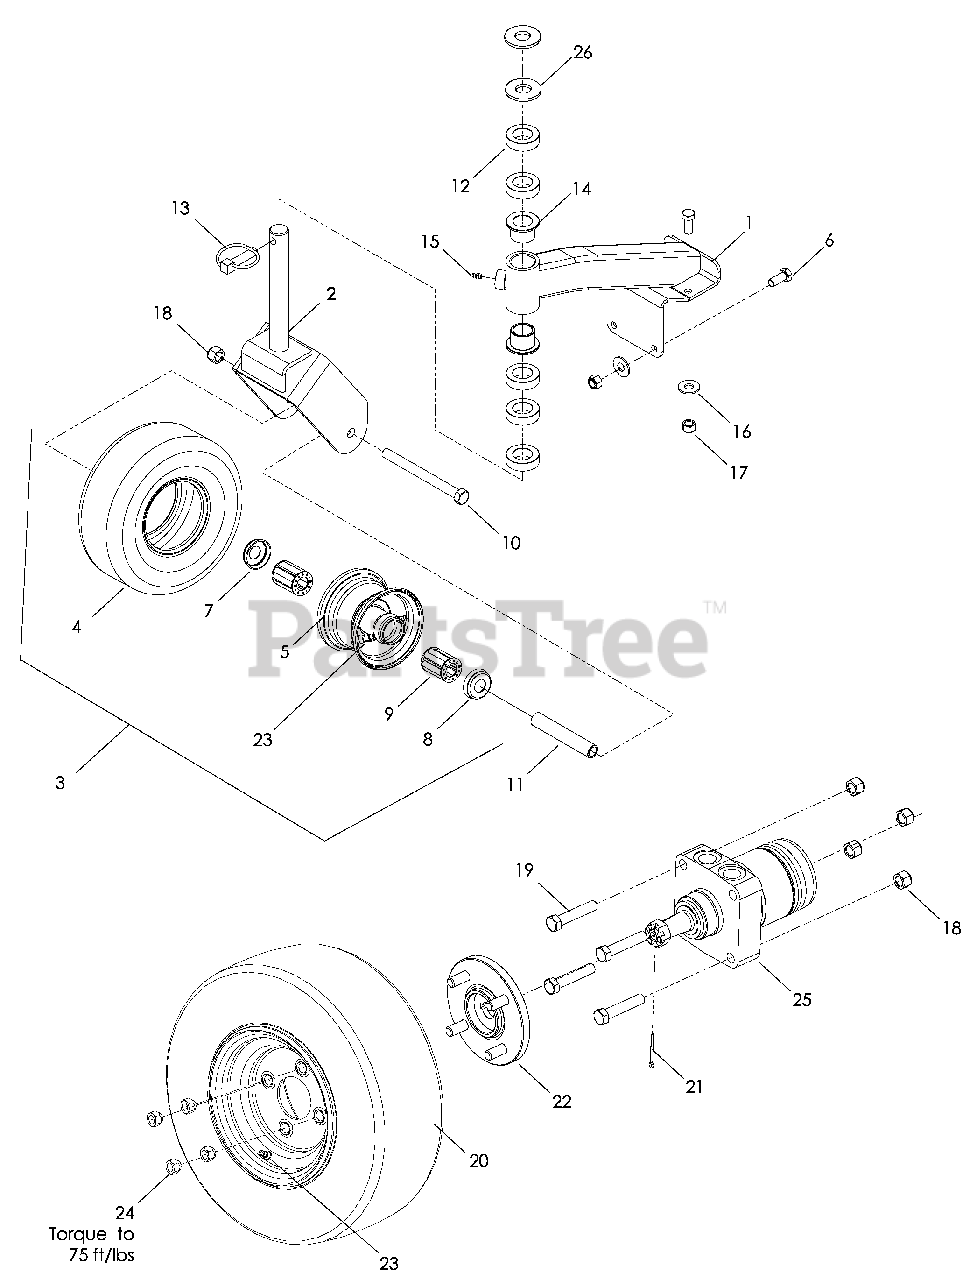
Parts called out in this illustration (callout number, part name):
1	CASTER ARM
2	CASTER FORK
3	WHEEL ASSEMBLY, CASTER
4	TIRE, CASTER
6	HCS 3/8-16 x 7/8
7	ENDCAP
8	NOTCHED ENDCAP
9	ROLLER BEARING
10	HCS ½-13 x 5½
11	SPACER, CASTER
12	SPACER, HEIGHT
13	LYNCH PIN 7/16
15	ZERK
16	WASHER 3/8 FLAT
17	NUT 3/8-16 HEX NYLOC
18	NUT ½ HEX NYLOC
19	HCS ½-13 x 2½
20	WHEEL ASSM, REAR 36
21	PIN 1/8 x 1½ COTTER
22	HUB, WHEEL
24	NUT, LUG ½
26	SPACER, HT ADJ ¼
